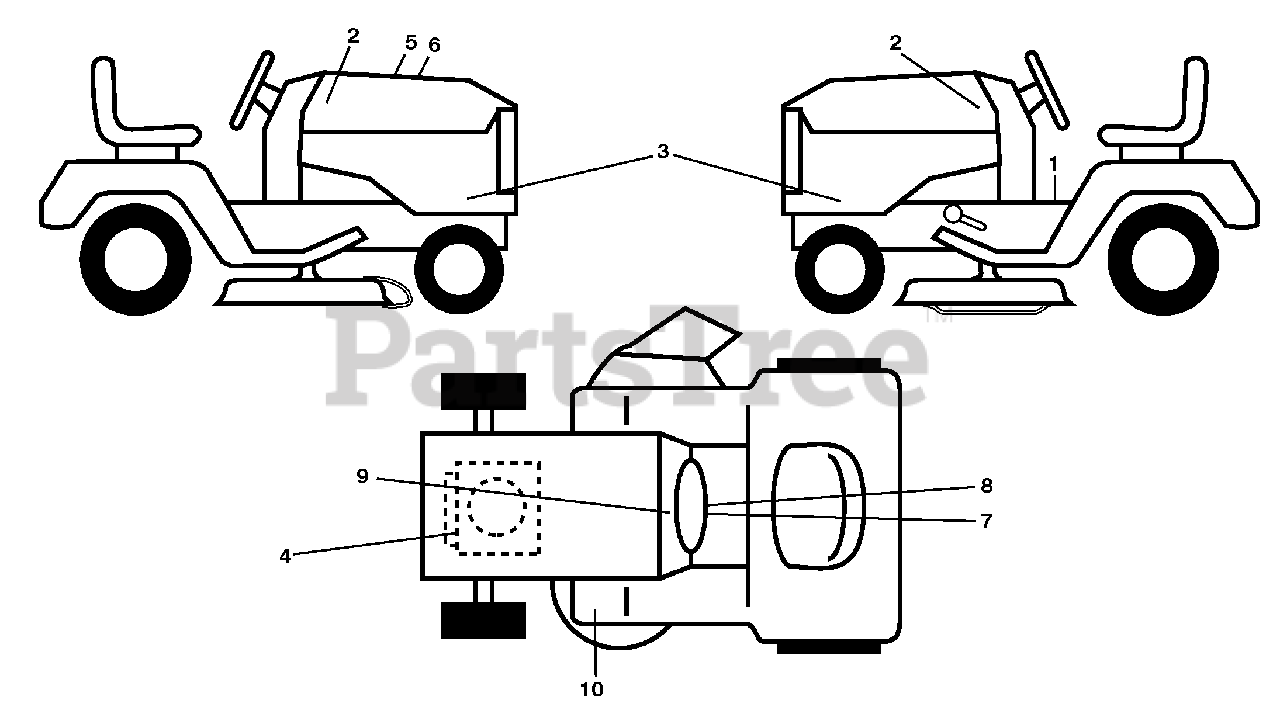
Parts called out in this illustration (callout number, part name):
1	Decal, Operators
2	Decal, Hood
3	Decal, Emblem Panel SD
4	Decal, Eng.
5	Decal, Customer Respons.
6	Decal, Replacement
7	Label Emiss. CA.
8	Decal, Warning Spark Arrestor
9	Decal, Battery Dnge/Poi
10	Decal, Pedal
